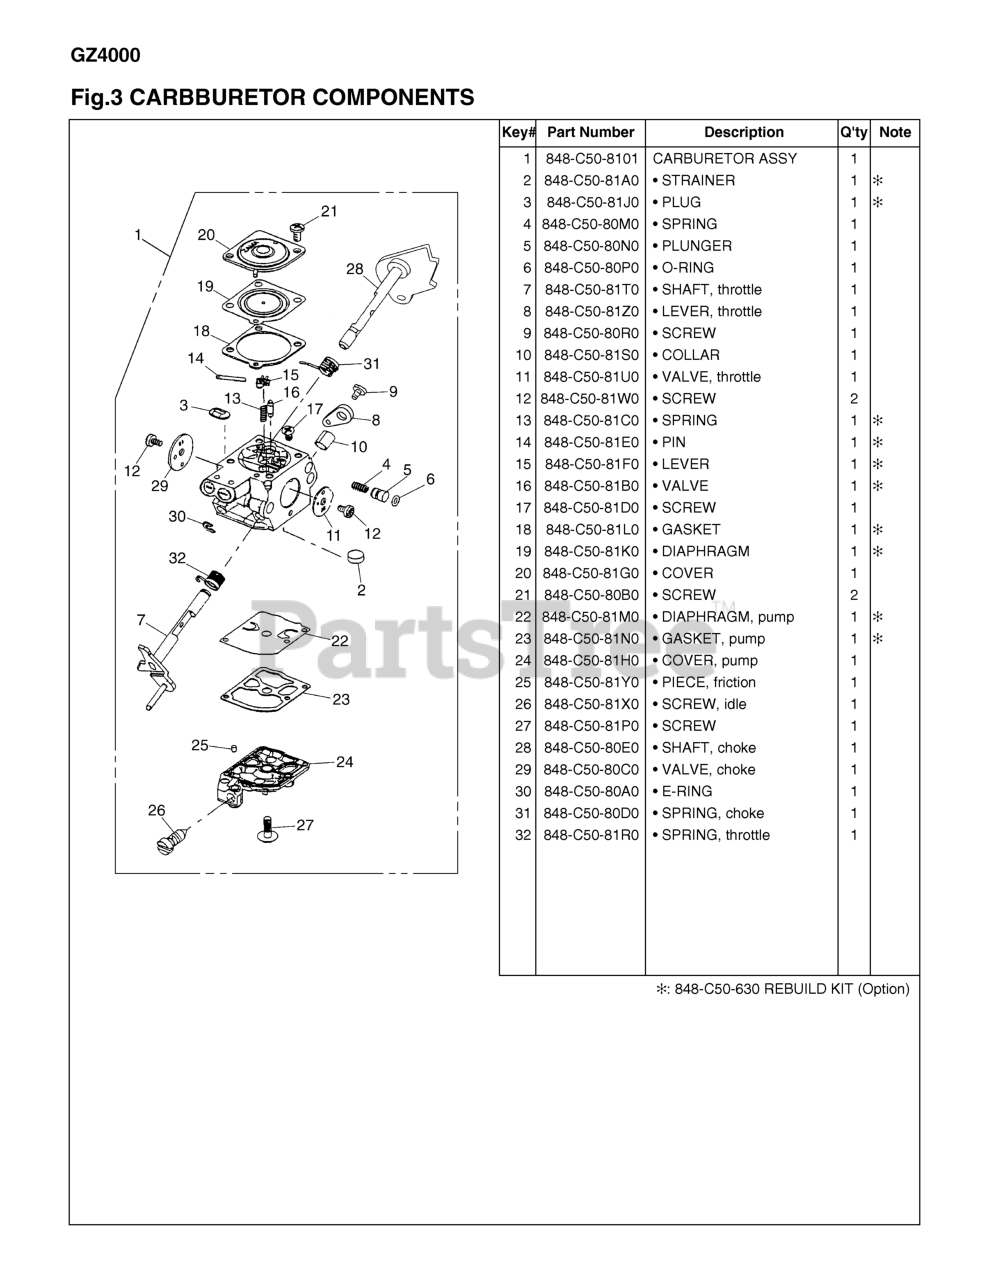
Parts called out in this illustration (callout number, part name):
1	CARBURETOR-ASSY
2	STRAINER
3	PLUG
4	SPRING
5	PLUNGER
6	O-RING
7	SHAFT
8	LEVER
9	SCREW
10	COLLAR
11	VALVE
12	SCREW
13	SPRING
14	PIN
15	LEVER
16	VALVE
17	SCREW
18	GASKET
19	DIAPHRAGM
20	COVER
21	SCREW
22	DIAPHRAGM
23	GASKET
24	COVER
25	PIECE
26	SCREW
27	SCREW
28	SHAFT
29	VALVE
30	E-RING
31	SPRING
32	SPRING
NI	REBUILD KIT
